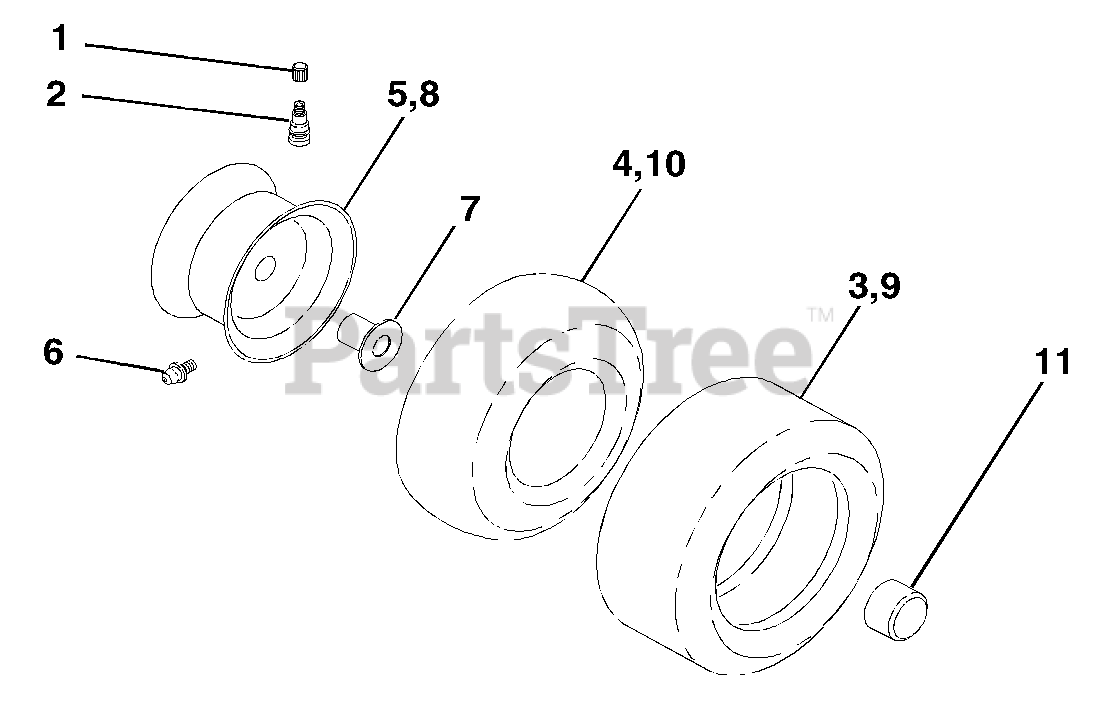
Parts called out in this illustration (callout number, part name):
1	Cap Valve Tire
2	Stem Valve
3	Tire F Ts 15 X 6 0 - 6 Service
4	Tube Front (Service Item Only)
5	Rim Asm 6" front Silver Service
6	Fitting Grease (Front Wheel Only)
7	Bearing Flange (Front Wheel Only)
8	Rim Asm 8" rear Silver Service
9	Tire R Ts 20 x 10-8 C Service
10	Tube Rear (Service Item Only)
11	Cap Axle Blk 1 50 X 1 00
